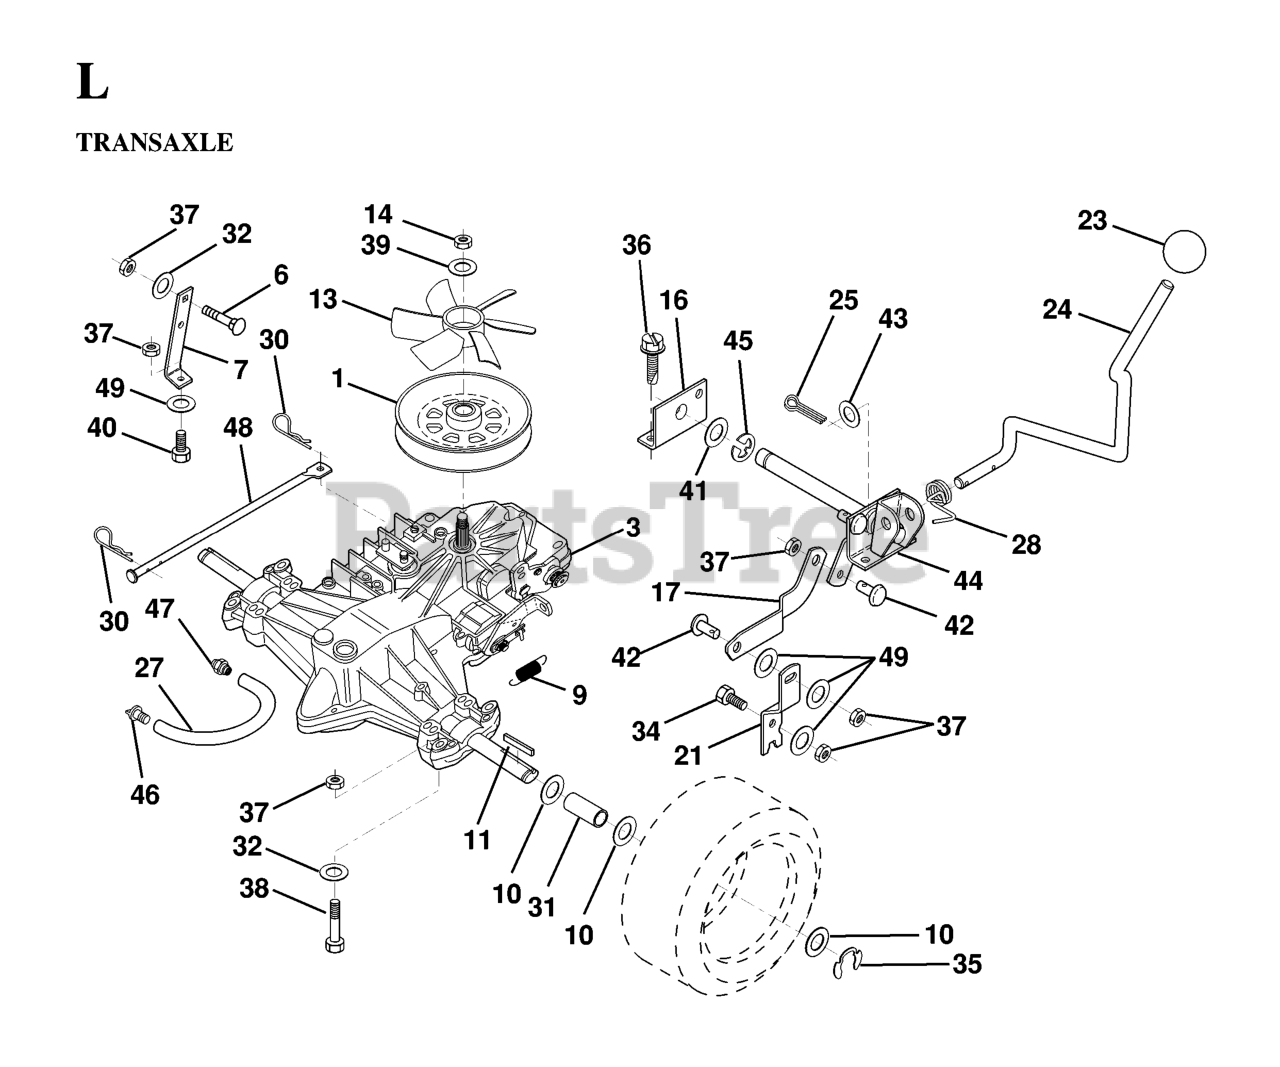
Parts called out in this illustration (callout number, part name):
1	PULLEY.V-GROOVE
6	RP BOLT 5/16-18 X3/4 ZN/YEL GR
9	SPRING,BRAKE RETURN
11	SQUARE KEY
13	FAN.TRANSMISSION.HYDRO.6"
16	SUPPORT, SHIFT HANDLE
17	LINK, SHIFT
21	LEVER, SHIFT
23	KNOB.DUCKHEAD.1/2
24	ROD, SHIFTER
25	PIN COTTER
27	LINE FUEL HYD 4"
28	SPRING, TORSION
30	RETAINER M
31	SPACER SPLIT
32	WASHER
34	BOLT RB
36	SCREW
37	NUT.71038.31-18.HEX.NYLOCK
38	BOLT HEX 5/16-18 GR 5
40	BOLT
41	Washer 21/32 x 1-1/4 x 13 Ga.
43	WASHER
44	SHAFT PIVOT ASMBLY
45	RETAINING RING LT
46	CAP, VENT ASSY
47	O-RING KIT 70110
49	WASHER M
